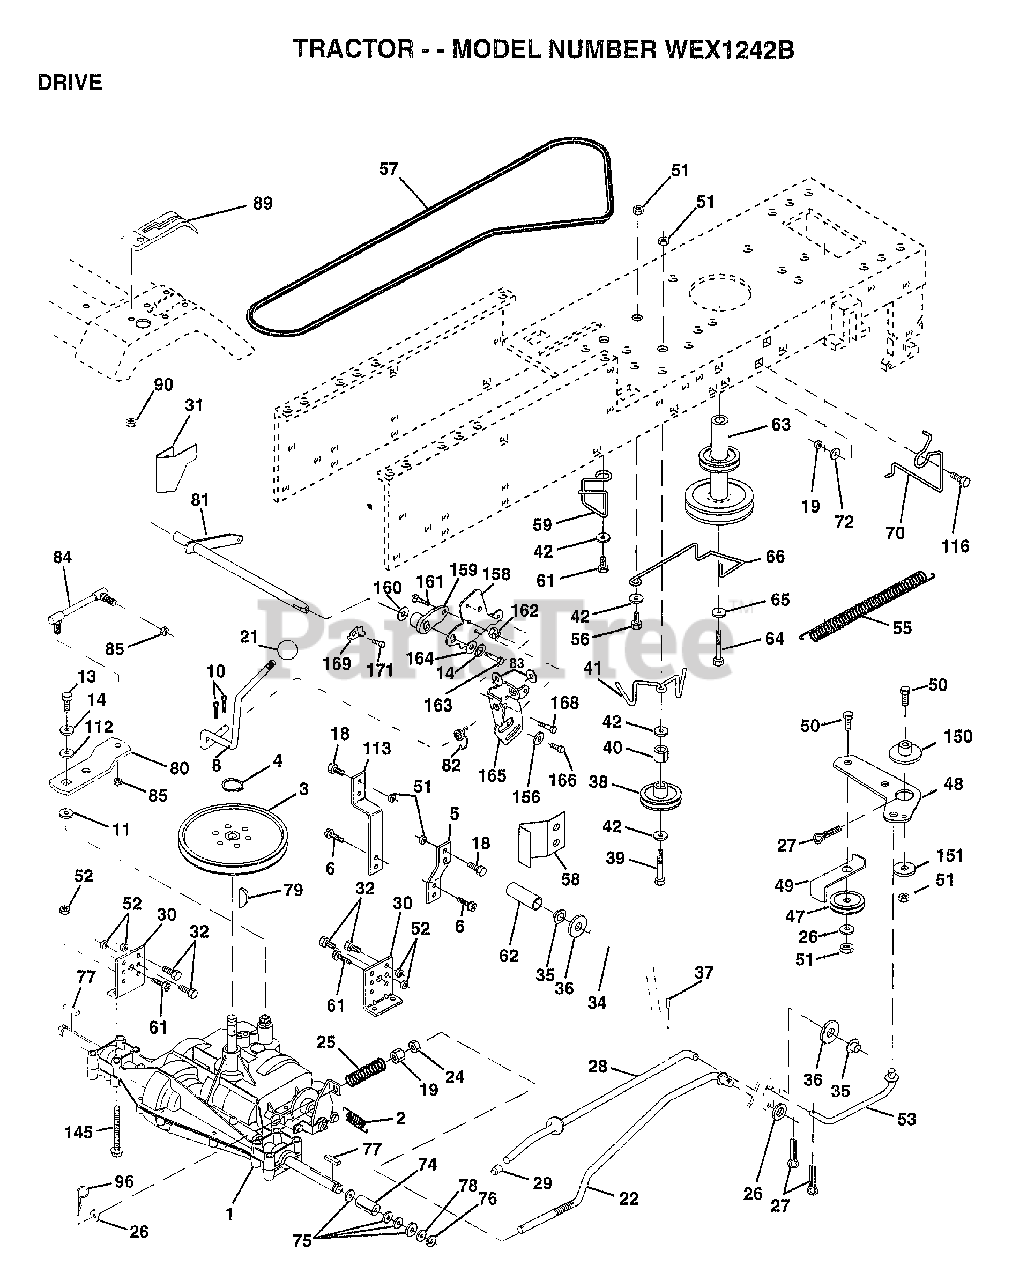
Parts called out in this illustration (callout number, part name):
2	SPRING.BRAKE.RETU
3	PULLEY TRANS
5	STRAP TORQUE
6	SCREW
8	ROD.SHIFT.FENDER.ADJ.LT.CRD
10	PIN COTTER 1/8
11	WASH-SHFT PLT LT
13	BOLT.1/4-28.W/PAT
14	LOCKWASHER
18	BOLT
19	NUT
21	KNOB T (1/2-HOLE)
22	BRAKE ROD
24	NUT
25	SPRING ROD LT
26	WASHER
27	COTTER PIN
28	ROD.BRAKE.PARK.LT
29	PLUNGER CAP T
30	TRANSAXLE MTG BKT
31	"KEEPER,BELT LH T"
32	BOLT
34	SHAFT ASM-PEDAL F
35	NYLON BEARING
36	WASHER LT
38	FLAT IDLER PULLEY
39	BOLT
40	SPACER T
41	"KEEPER,BELT.IDLER FLAT"
42	WASHER
48	BELLCRANK.CLUTCH
49	RETAIN BELT
53	"LINK, CLUTCH T"
55	"SPRING, RETURN LT"
58	"KEEPER,BELT RH T"
59	KEEPER BELT CNTSP
61	SCREW
62	PEDAL COVER T
63	PULLEY.ENGINE
64	BOLT
65	LOCKWASHER
66	KEEPER-BELT
70	KEEPER BELT ENG
72	WASHER
74	SPACER AXLE
75	WASHER
76	E-RING LT
77	SQUARE KEY
78	WASHER
80	"ROD,LINK SHIFT"
81	SHAFT.ASM.CROSS
82	"SPRING,TORSION"
83	WASHER
84	LINK.TRANSAXLE
85	NUT.CNT.LOCK.1/4
86	BUSHING
87	WASHER D
88	KLIP RING
89	CONSOLE.SHIFT.LT.5SP.GREY
90	NUT
96	RETAINER M
112	WASHER LT
113	"STRAP,TORQUE"
116	BOLT RDHD 3/8-16
145	BOLT.HEX.FLGHD
150	BUSHING.BELLCRANK.GRD.DR
151	WASHER
156	WASHER.SRRTD.5/16
158	BRKT.SHIFT.MOUNT
159	HUB.SHIFT
160	WASHER
161	BOLT T
164	WASHER.5/8X.281X10GA
165	BRKT.PIVOT.LEVER
166	SCREW.5/16-18X5/8
168	BOLT.SHOULDER.5/16-18X.561
169	PLATE.FASTENING
171	SCREW LT
